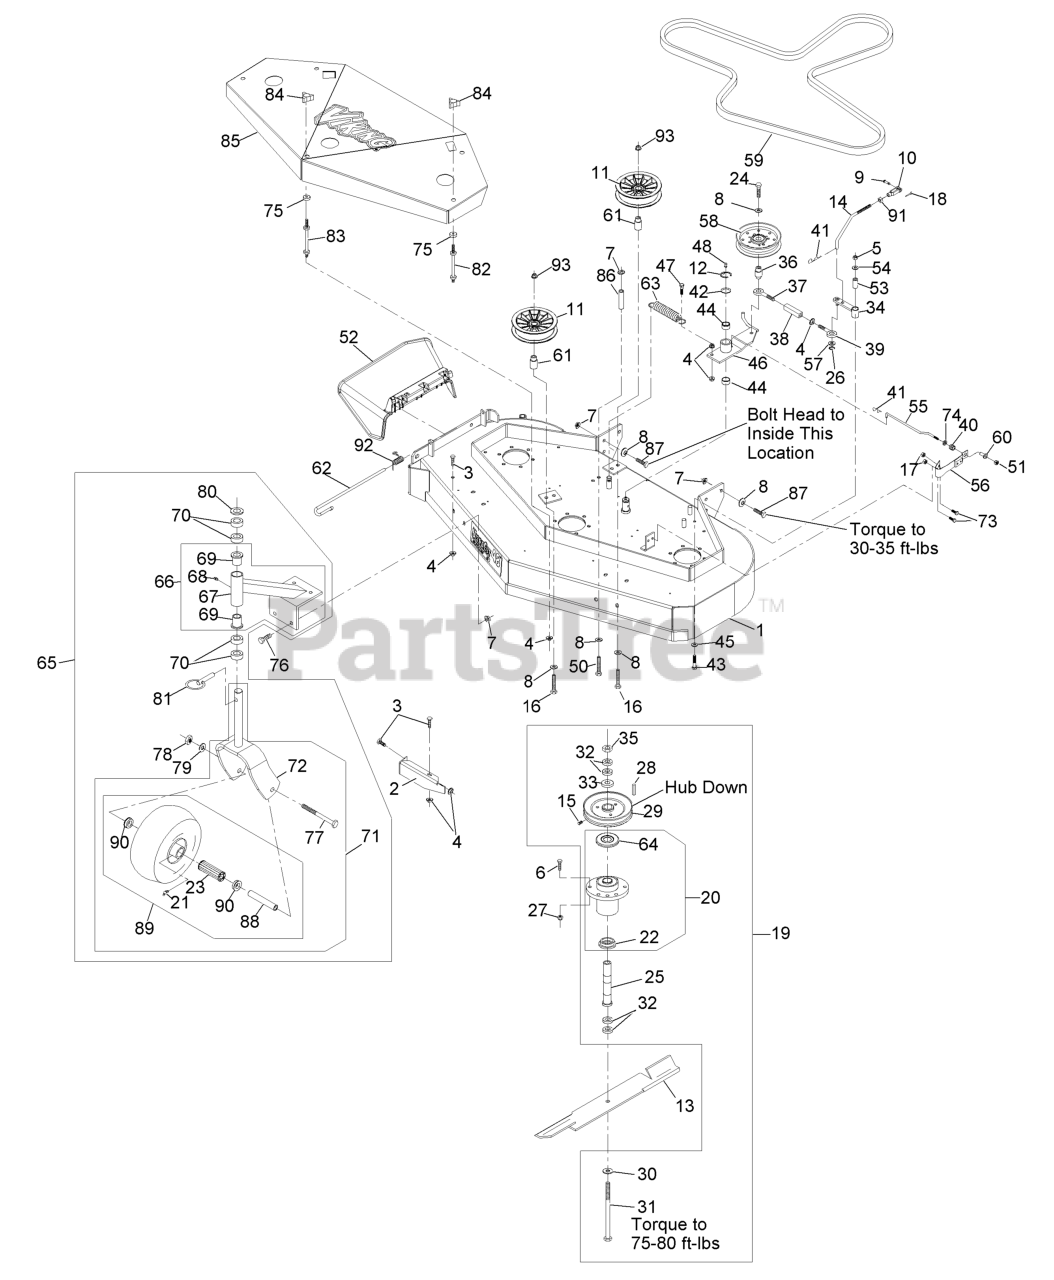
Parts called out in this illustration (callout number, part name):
1	DECK-SERVICE, 48
2	BAFFLE-DOGLEG
3	SCREW-HH
5	NUT-LOCK, NI
6	SCREW-HH
7	NUT-HHF, WHIZ
8	WASHER-BELLEVILLE
9	PIN-CLEVIS
10	YOKE-ADJUSTABLE
11	PULLEY,IDLER 5"
12	RING-RETAINING, EXT
14	ARM-LINKAGE, ASSIST
15	SETSCREW
16	SCREW-HH
17	NUT-LOCK, NI
18	PIN-COTTER
19	ASM, CUTTER HOUSING OUTER
20	KIT, CUTTER HOUSING
21	FITTING-GREASE
22	SPACER-GUARD, BOTTOM
23	BEARING
24	SCREW-HH
25	TUBE-SPINDLE, SHORT
26	RING-RETAINING, EXT
27	NUT-LOCK, NI
29	SHEAVE
30	WASHER-SPRING
31	SCREW-CAP, HH
33	WASHER-RETAINER, SHEAVE
34	ARM-ASSIST, 32/36
35	NUT-HEX
36	BUSHING-ENGAGEMENT
37	EYEBOLT-THREAD, LH
38	BODY-TURNBUCKLE
39	EYEBOLT-THREAD, RH
40	SPRING-COMPRESSION
41	PIN-COTTER
42	WASHER-SPINDLE
43	SCREW-HH
44	SLEEVE-BEARING
45	WASHER-SPRING
46	IDLER ARM ASM
47	SCREW-HH, SPECIAL
48	FITTING-GREASE
50	SCREW-HH
51	NUT-LOCK, NI
52	CHUTE DEFLECTOR XRK M056
53	TUBE-PIVOT
54	WASHER-FLAT
55	ROD-BRAKE
56	PAD AND SPRING ASM
57	WASHER-PLAIN
59	BELT,BLADE 48
60	SPACER-FLANGED
61	BUSHING-IDLER
62	PIN-CHUTE
63	SPRING-EXTENSION
64	GUARD-BEARING, TOP
65	ASM-CASTER MNT W/WEIGHT
66	ASM,CSTR SUPPORT W/WEIGHT
68	FITTING-GREASE
69	BEARING-FLANGED
70	SPACER-CASTER
71	ASM,CASTER/WHEEL
72	FORK-CASTER
73	SCREW-HH
74	RING-PUSH ON
76	SCREW-HH
77	SCREW-HH
78	NUT-HH
79	WASHER-LOCK
80	WASHER-FLAT
82	STUD-SHIELD, BELT (SHORT)
83	STUD-SHIELD, BELT (LONG)
84	KNOB-3 PRONG
85	ASM,SHIELD W/DECALS 48 VI
87	SCREW-HH
89	KIT, SP CASTER WHEEL REPL
90	BUSHING
91	NUT-HEX
92	SPRING, TORSION
93	NUT-HF, NI
